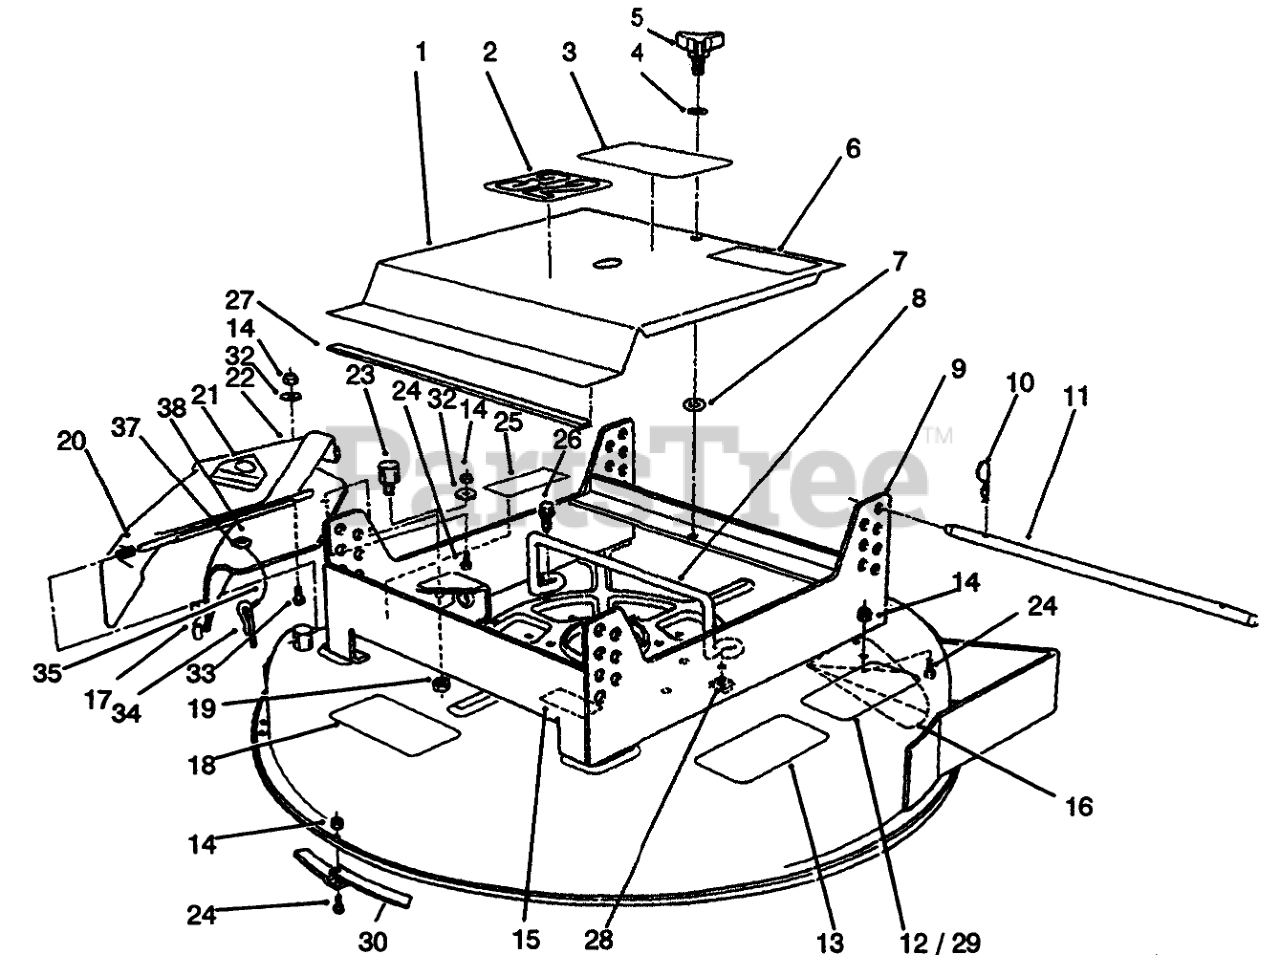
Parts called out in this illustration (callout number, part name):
1	Cover (Incl. Ref.#2-7 & 27)
2	DECAL
3	DECAL-PROLINE
4	WASHER-FLAT
6	DECAL-HOT
7	RING-RETAINING
8	GUIDE-BELT
9	32 INCH DECK ASM
10	PIN-HAIR
11	ROD-SUPPORT
12	DECAL
13	Decal
14	NUT-LOCK, NI
15	DECAL-DANGER
16	Kicker
17	MULCHER COVER ASM
18	DECAL-DANGER, THROWN OBJECT
19	NUT-LOCK, SIDE
20	SPRING
21	DECAL-DANGER
22	Deflector Ass-y (Incl. Ref.#21)
23	POST-PIVOT
24	SCREW-HH
25	DECAL-DANGER
26	SCREW-HHF
27	STRIP-MAGNETIC
28	NUT-RETAINER
29	Decal-Height of Cut 2-5"
30	Ring-Deck
32	WASHER-PLAIN
33	SCREW-HH
34	PIN-LOCKING, CHUTE
35	LANYARD
37	WASHER-PLAIN
38	RIVET-BLIND
